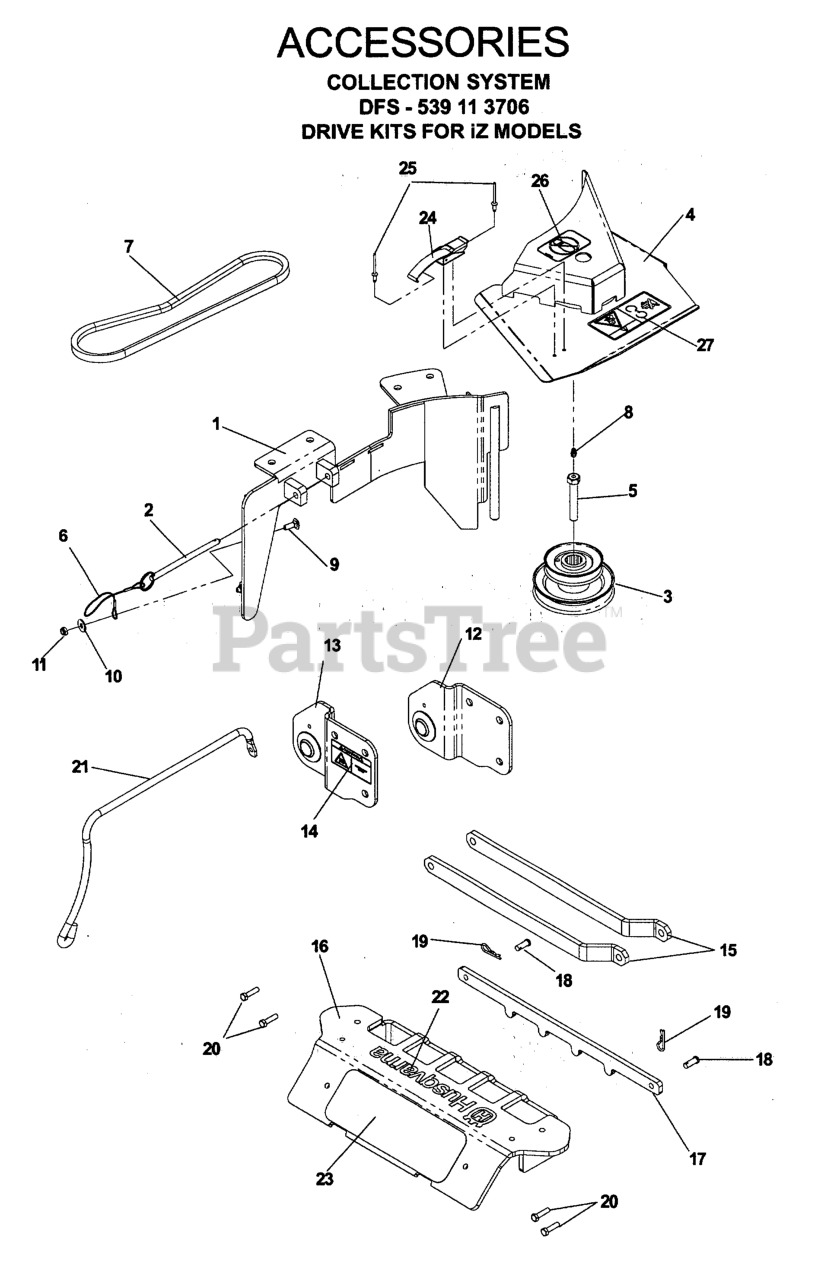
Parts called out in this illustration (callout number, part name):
1	BLOWER DECK PLATE
3	42/48 LG DBL HEX STACK PULLEY
4	BELT SHIELD ASSY 48"
5	HCS, 7/16-20 X 2 1/2, GR8
8	ZERK
9	RHSNB 1/4C X 3/4
10	WASHER 1/4 FLAT
11	JAM NUT 1/4C (2 2 PW01)
12	HITCH BRACKET WLD
13	HITCH BRACKET WLDMT, RT, MID
14	DECAL, HOT SURFACE
16	WEIGHT BAR, IZ
17	HOLD DOWN, WEIGHT BAR
18	CLEVIS PIN
19	RETAINER SPRING
20	HCS 5/16C X 1 1/4
21	HOSE SUPPORT
22	DECAL, HUSQ 12" BLUE
23	ANTI-SKID PAD
24	DRAW LATCH
25	RIVET, BLIND, 5/32 DIA
26	DECAL, NO STEP
27	DECAL, BELT DRIVE
